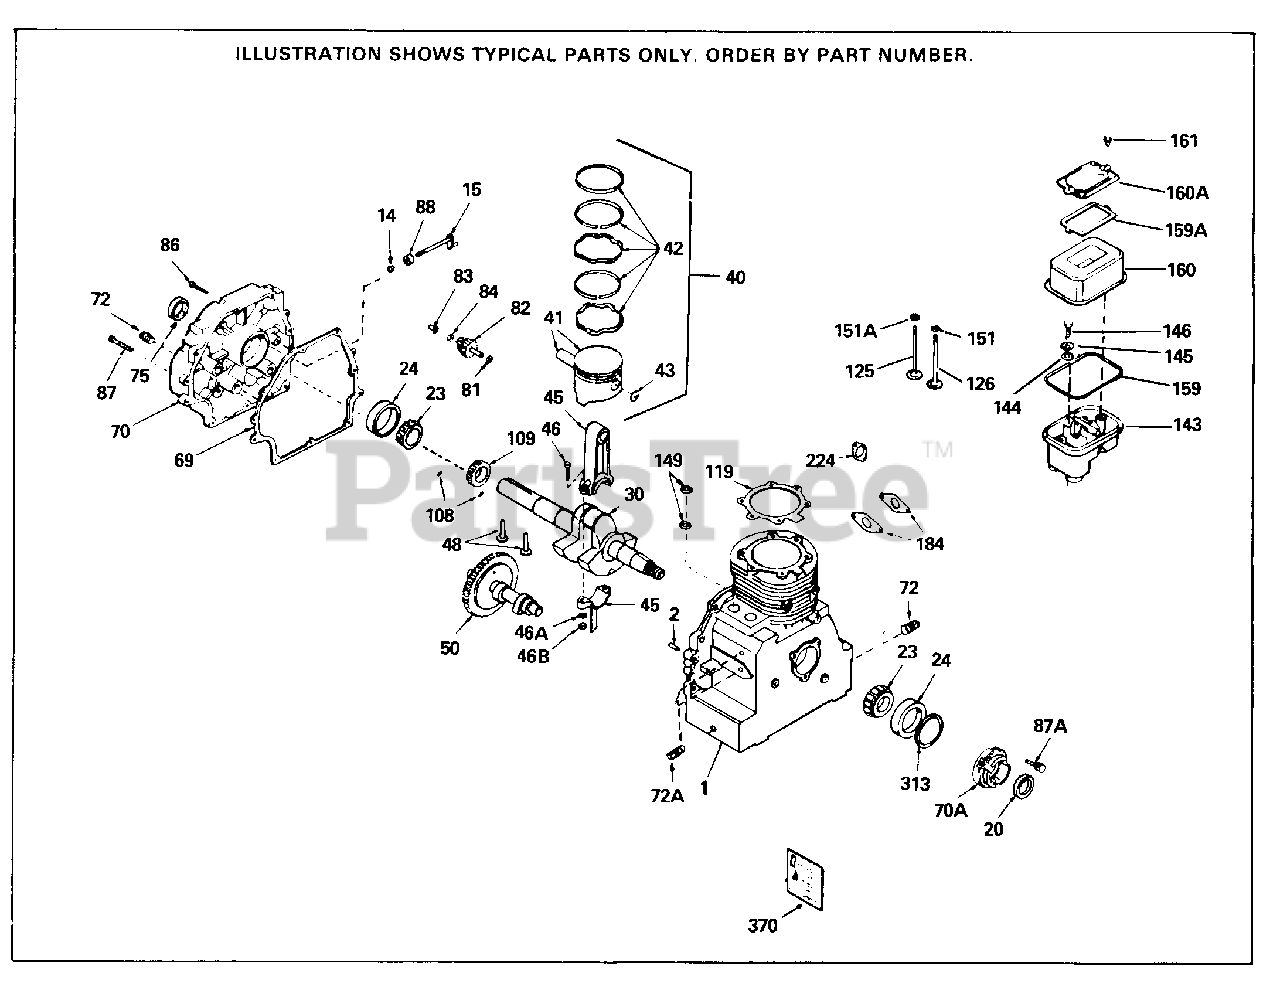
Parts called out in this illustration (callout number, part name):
1	"Cylinder (Incl. 2, 72, 72A & 75) 3-5/ 16"
2	Dowel Pin
14	Retaining Ring
15	Rod Assy., Governor
20	Seal, Oil
23	Bearing, Tapered roller
24	Cup, Bearing
30	Crankshaft (Incl. 23, 24, 108 & 109)
40	Piston, Pin & Ring Set (.020" OS)
40	Piston, Pin & Ring Set (Std.) 3-5/16" Bore
40	Piston, Pin & Ring Set (.010" OS)
41	Piston & Pin Ass'y. (Incl. 43)(Std.) 3-5/16"
41	Piston & Pin Ass'y. (Incl. 43) .010"O S
41	Piston & Pin Ass'y. (Incl. 43) .020"O S
42	Ring Set (Std.) (3-5/16" Bore)
42	Ring Set (.010" OS)
42	Ring Set (.020" OS)
43	Piston pin retaining ring
45	Connecting Rod Ass'y. (Incl. 46,46A,4 6B)(Std.)
45	Connecting Rod (Incl. 46,46A,46B) .01 0" US
45	Connecting Rod (Incl. 46,46A,46B) .02 0" US
46	Bolt, Connecting rod
48	Lifter, Valve
50	Camshaft (MCR)
69	Gasket, Cylinder cover
70	Cylinder Cover Ass'y. Incl. 2,14,15,2 0,72,88
70A	Cover, Cylinder
72	Plug, Pipe (Square head, 3/8-18)
72A	Plug, Pipe (Square head, 1/8-27)
75	Seal, Oil
81	Washer, Flat
82	Gear & Shaft Assy., Governor
83	Governor Spool
84	WASHER
86	Screw, 1/4-20 x 2"
87	Screw, 1/4-20 x 1"
87A	Screw, 5/16-18 x 7/8"
88	Spacer, Governor rod
108	Pin, Crankshaft gear
109	Gear, Crankshaft
119	Gasket, Cylinder head
125	Exhaust Valve (Std.) Not incl. w/shor t block
126	Intake Valve (Std.) Not incl. w/short block
143	Housing Rocker Arm Not incl. w/shortb lock
144	"O" Ring
145	Washer Not included with short block
146	Screw (Not included with short block)
149	"O" Ring
151	"O" Ring (Intake only)
151A	"O" Ring (Exhaust only)
159	"O" Ring
159A	Gasket, Breather
160	Rocker Arm Cover Not incl. w/short bl ock
160A	Breather Body Assy. Not incl. w/short block
161	Screw, 10-32 x 5/8"
184	Gasket, Carburetor
224	Gasket, Intake pipe
313	"O" Ring
370	Decal, Instruction
